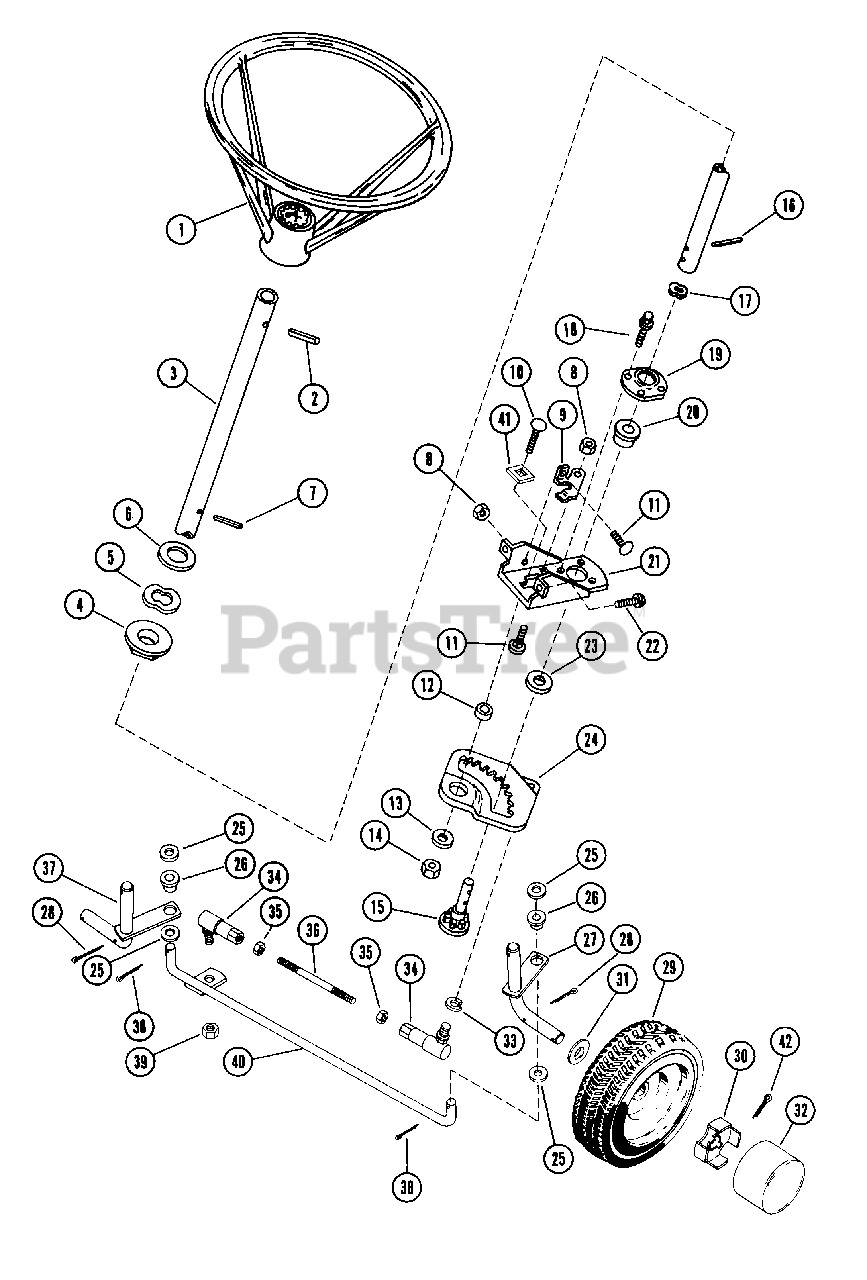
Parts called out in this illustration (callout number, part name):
1	STEERING WHEEL
2	PIN-ROLL .250X1.75
3	STEERING SHAFT
4	FLANGE BUSHING
5	SPRING WASHER
6	WSHR-FL-STL .755X1.375X.062 PL
7	PIN-ROLL .188X1.25
8	NUT-LK-CTR .250-20 PL
9	ADJUSTMENT BRACKET
10	BLT-RDHDSQSHNK .38-16X1.00 PL
11	BLT-RDHDSQNK .25-20X.62 PL
12	SPACER .380X.750X.236
13	WSHR-FL-STL .390X1.500X.125
14	NUT-LK-CTR .375-16 GR A PL
15	STEERING PINION
16	PIN-ROLL .188X1.00
17	WAVE WASHER .531X.781X.125FH
18	SCR-TAP 10-24X.25 CRSLPH PL 1A
19	RETAINING PLATE
20	BSHG-FLG .625X1.156X.375 SI
21	STEERING BRACKET
22	BLT-SERHFWH .31-18X.50 PL
23	WSHR-FL-STL .630X1.005X.062 PL
24	STEERING GEAR
25	WSHR-FL-STL .505X.875X.024 PL
26	BSHG-FLG.500X.625X.312X.750NY
27	L H WHEEL SPINDLE
28	PIN-COTR .12 X 1.25 PL
29	FRONT WHEEL ASSEMBLY
29	TIRE 4.10/3.50-4
29	WHL
29	ZERK FITTING
29	BSHG-FLG .750X1.380X.750X1.557
29	BRG-BALL .752X1.50X.50
30	SPINDLE CUP
31	SPINDLE WASHER
32	HUB CAP
33	WSHR-LK .375X.115 HVY PL
34	BALL JOINT
35	NUT .375-24 PL
36	STEERING LINK
37	R H WHEEL SPINDLE
38	PIN-COTR .12X1.0 PL
39	NUT-LK-CTR .375-24
40	TIE ROD
41	WASHER
42	PIN-COTR .12X1.0 PL
